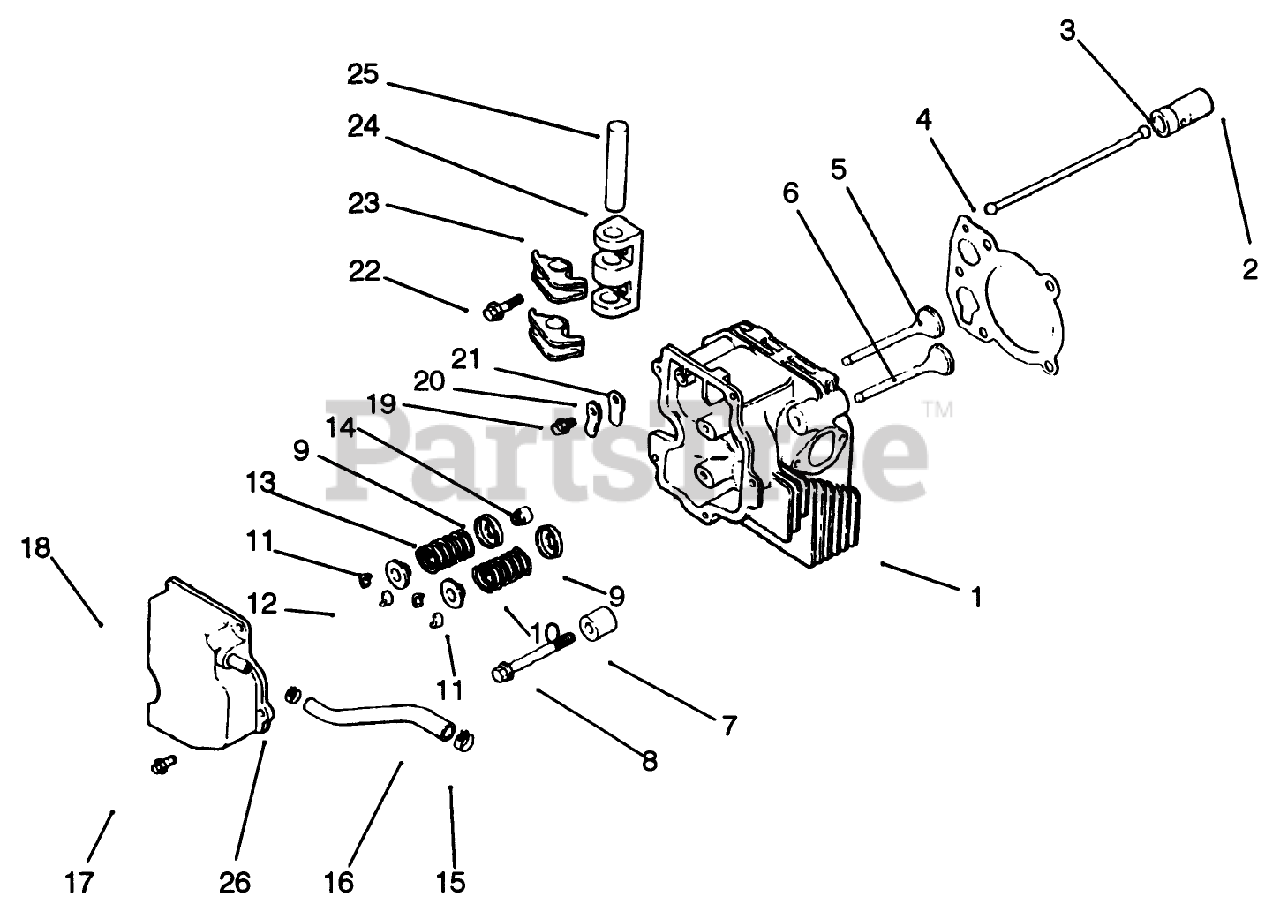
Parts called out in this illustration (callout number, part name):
1	Cylinder Head
2	Lifter-Valve
3	Rod-Push
4	Gasket-Cylinder Head
5	Valve-Intake STD (Only On: 72042, 72063, 72062, 72043)
6	Valve-Exhaust STD (Only On: 72042,72043,72062,72063)
7	Spacer-Head Bolt
8	Screw-Cylinder Head
9	Retainer-Spring
10	Spring-Valve Exhaust (Only On: 72042,72043,72062,72063)
11	Cap-Valve Spring
12	Kit-Retainer
13	Spring-Valve, Intake
14	Seal
15	Clamp
16	Hose-Breather (Only On: 72042, 72063, 72062, 72043)
18	Cover-Valve W/Nipple (Only On: 72042, 72063, 72062, 72043)
20	Retainer-Reed
23	Arm-Rocker
24	Bridge-Rocker Arm
25	Shaft-Rocker Arm
26	Clamp-Hose
